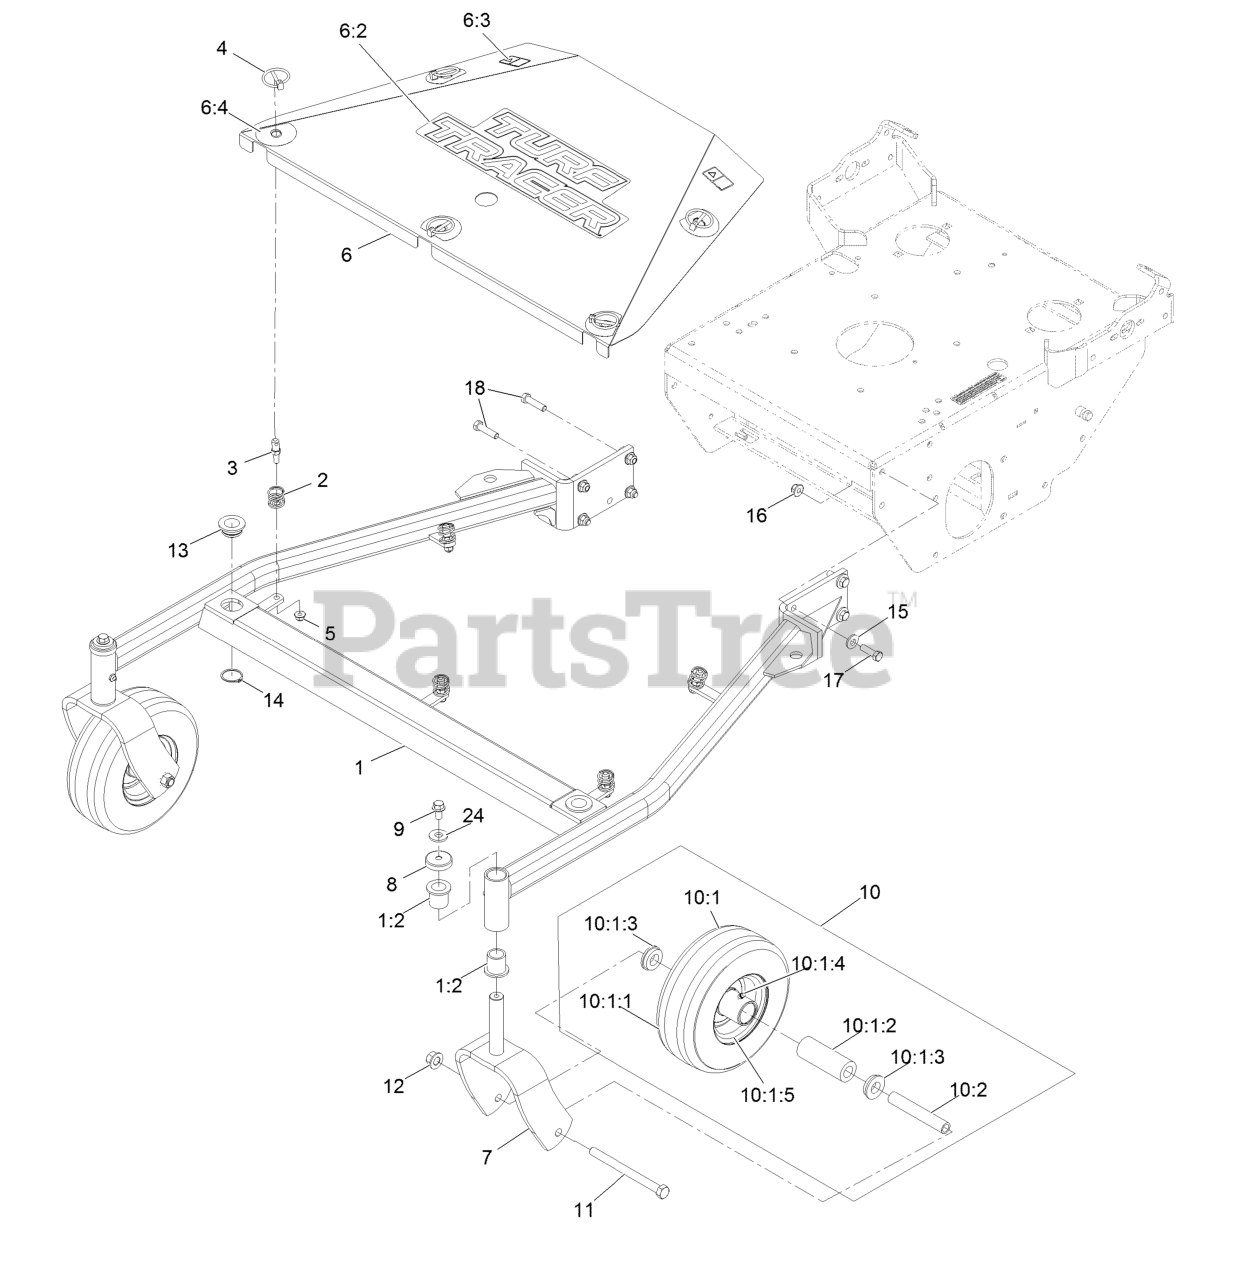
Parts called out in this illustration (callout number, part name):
1	ASM, Frame W/ Bushings, 52
1:2	Bearing-Flanged
3	Pin-Spring
4	Pin-Lynch
5	Nut-HF, NI
6	ASM, Shield W/ Decals, 52
6:2	Decal-Turf Tracer
6:3	Decal-Warning
6:4	Decal-Scratch Cover
7	Fork, Caster [red]
8	Cap, Dust
9	Screw-HHF
10	Kit,Semi-Pneumatic Wheel Replacement
10:1	Wheel And Tire ASM
10:1:1	Tire
10:1:2	Bearing
10:1:3	Bushing
10:1:4	Fitting-Grease
10:1:5	Wheel
11	Screw-HH
12	Nut-Lock
13	Bushing-Deck
14	Ring-Retaining
15	Washer-Belleville
16	Nut-HF, NI
17	Screw-HH
18	Screw-HH
